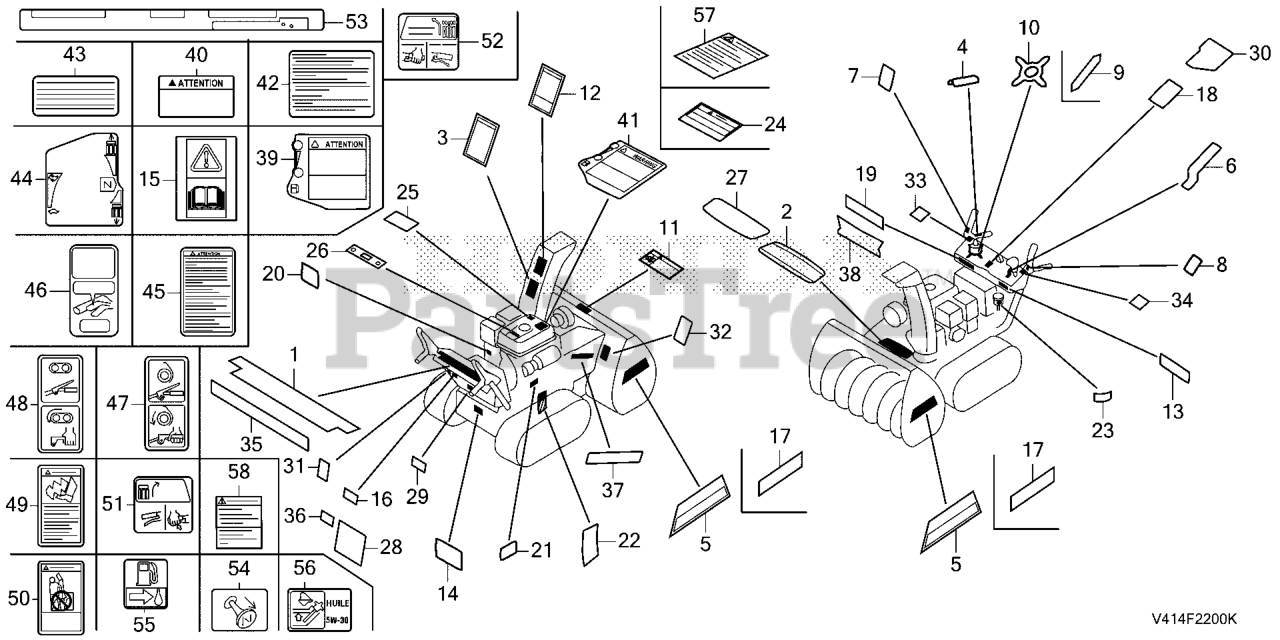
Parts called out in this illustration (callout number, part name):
3	LABEL, WARNING (E)
7	MARK, AUGER CLUTCH (A)
8	MARK, CLUTCH (A)
10	MARK, CHUTE OPERATION (Z)
12	MARK, DISCHARGE DANGER (E)
20	MARK, FUEL INDICATION (A)
21	MARK, OIL CAUTION (E)
25	MARK, EX. CAUTION (ENGLISH)
27	MARK, EMBLEM (HSS928A)
28	LABEL, OPERATION (DC START-E)
30	MARK, CHANGE (E)
32	MARK, DANGER (E)
33	MARK, R. TURN (E)
34	MARK, L. TURN (E)
35	MARK, ENGINE SWITCH (DC START-E)
36	MARK, CHOKE (E)
37	MARK, HONDA
38	MARK, HONDA (B)
41	MARK, FUEL WARNING COMBINATION (ENGLISH)
57	MARK, FUEL WARNING (ENGLISH)
